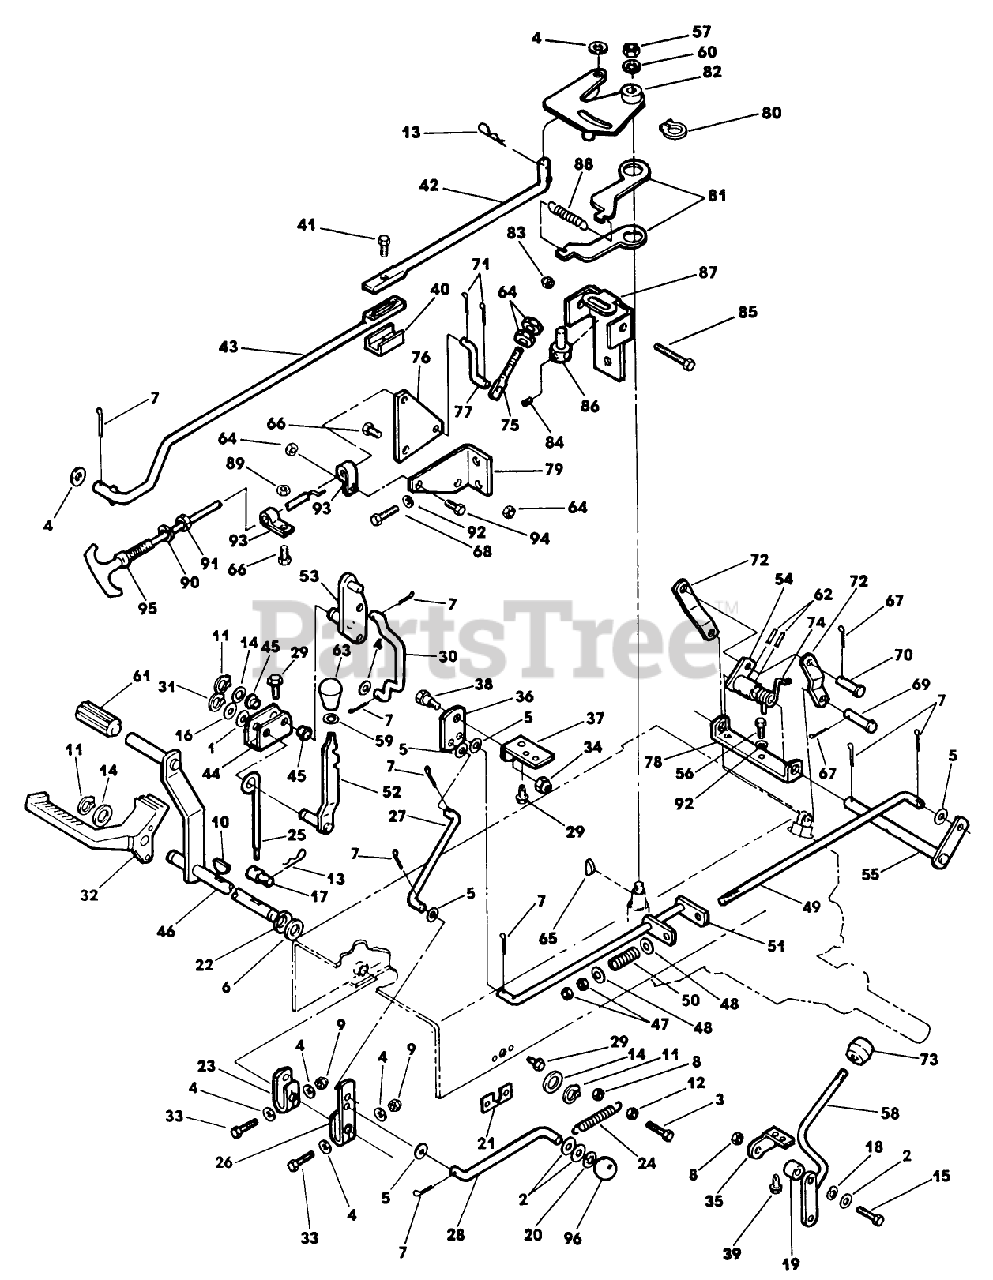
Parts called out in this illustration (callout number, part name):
4	WASHER
8	NUT
9	NUT-LOCKING
13	PIN-HAIR
14	WASHER
15	SCREW
22	WASHER-CUPPED
31	RING - RETAINING
34	NUT
37	BRKT-BRAKE PIVOT
40	CLAMP
50	SPRING-BRAKE
52	CRUISE RELEASE AY.
56	SCREW - HEX
57	NUT
60	WASHER
66	SCREW
68	SCREW-THD ROLL, HWH
74	SPRING,TORSION
76	LEVER - PIVOT R/B709575
79	BRACKET,CABLE
80	RING - RETAINING
84	SETSCREW
88	SPRING-EXTENSION
89	NUT-LOCK, CONE
91	NUT-HEX
